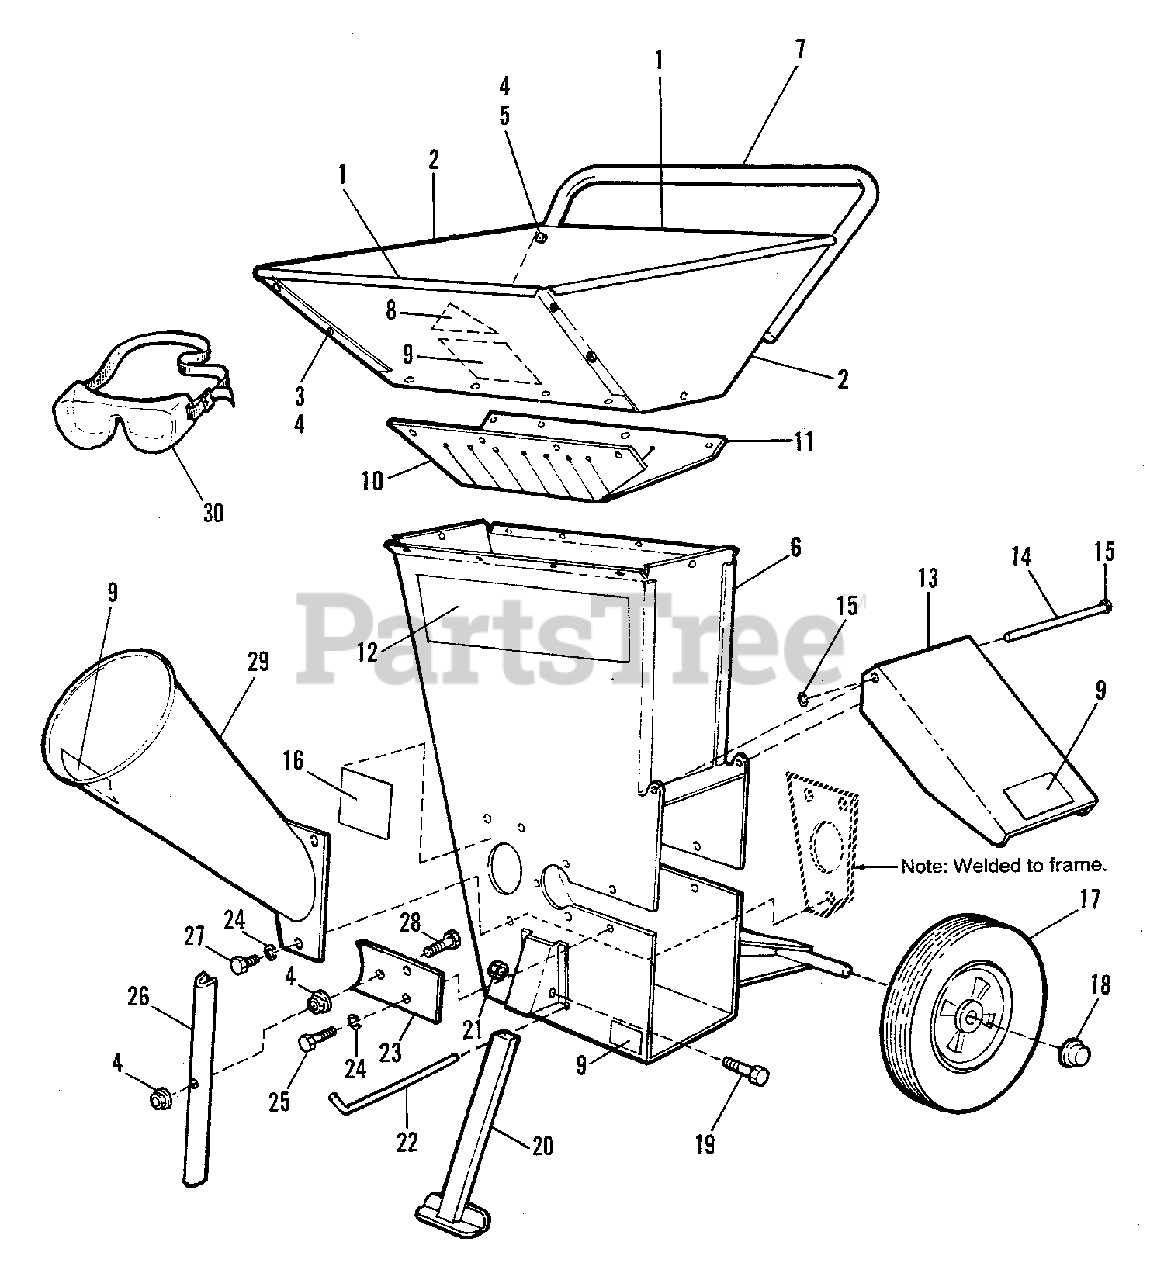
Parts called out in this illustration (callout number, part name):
1	HOPPER FRONT & BACK
2	HOPPER END
3	SCREW, Truss Head, Phillips, 1/4-20 x 5/8
4	NUT, Hex Flange, Whiz Lock, 1/4-20
5	CAPSCREW, 1/4-20 x 1-1/2
6	MAIN FRAME
8	DECAL, OPEI
9	DECAL, Danger
10	GUARD, Cone Side
11	GUARD, Engine Side
12	DECAL
13	DEFLECTOR, Discharge
14	DEFLECTOR, Rod
15	NUT, Push, 1/4
18	NUT, Push, 5/8
19	CAPSCREW, Hex, 5/16-18 x 1-3/4
21	NUT, Nylock, 5/16-18
22	ROD, Screen
23	PLATE, Closure
24	LOCKWASHER, 5/16
25	CAPSCREW, Hex, 5/16-18 x 1/2
26	ROD HOLDER
27	CAPSCREW, Hex, 5/16-18 x 3/4
28	SCREW, Truss head, Phillips, 1/4-20 x 1-1/2
29	CONE, Chipper Hopper
